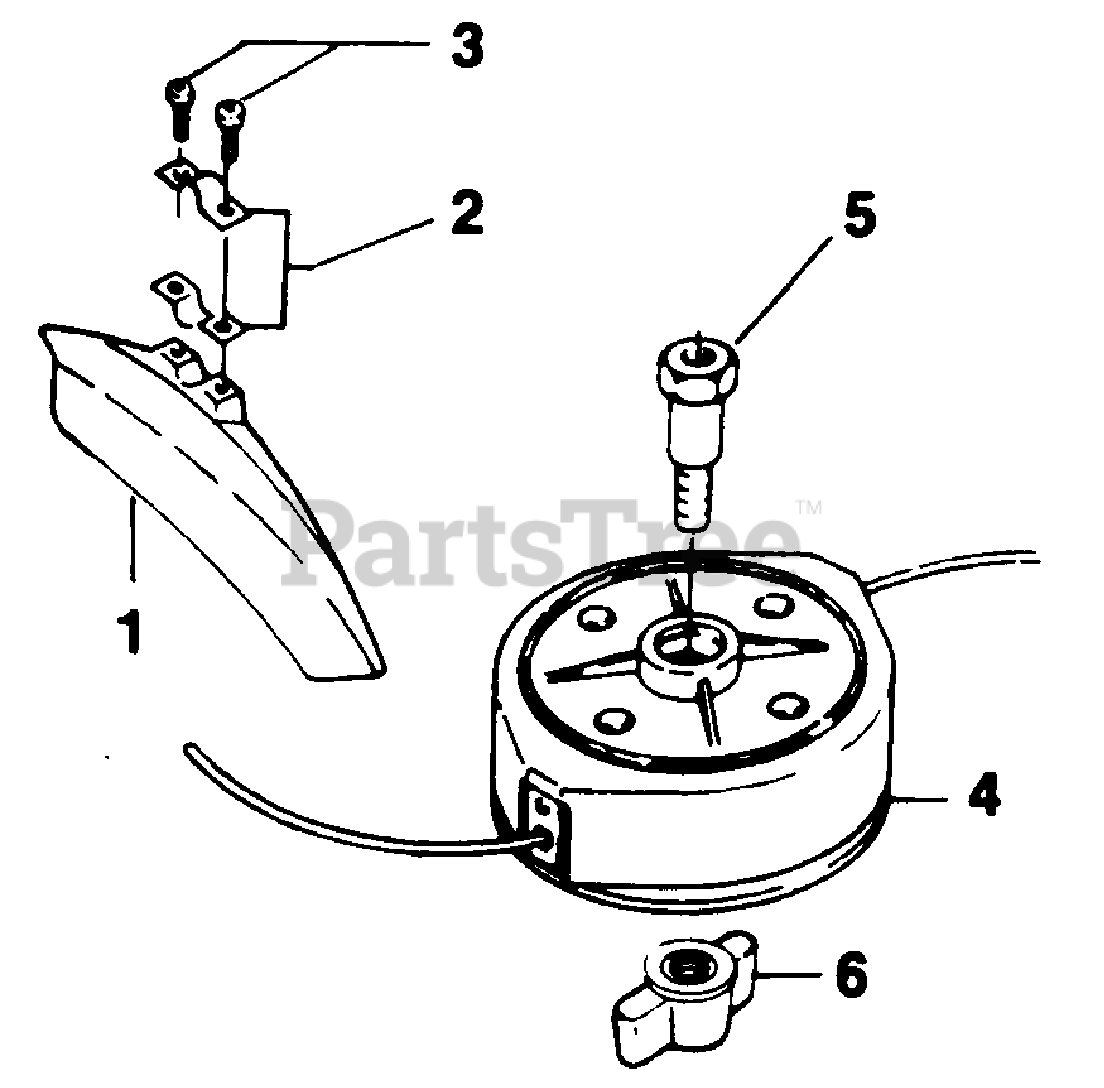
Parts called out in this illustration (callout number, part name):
1	DEFLECTOR
2	STAY- Deflector
4	STRINGHEAD
5	BOLT- Shaft
